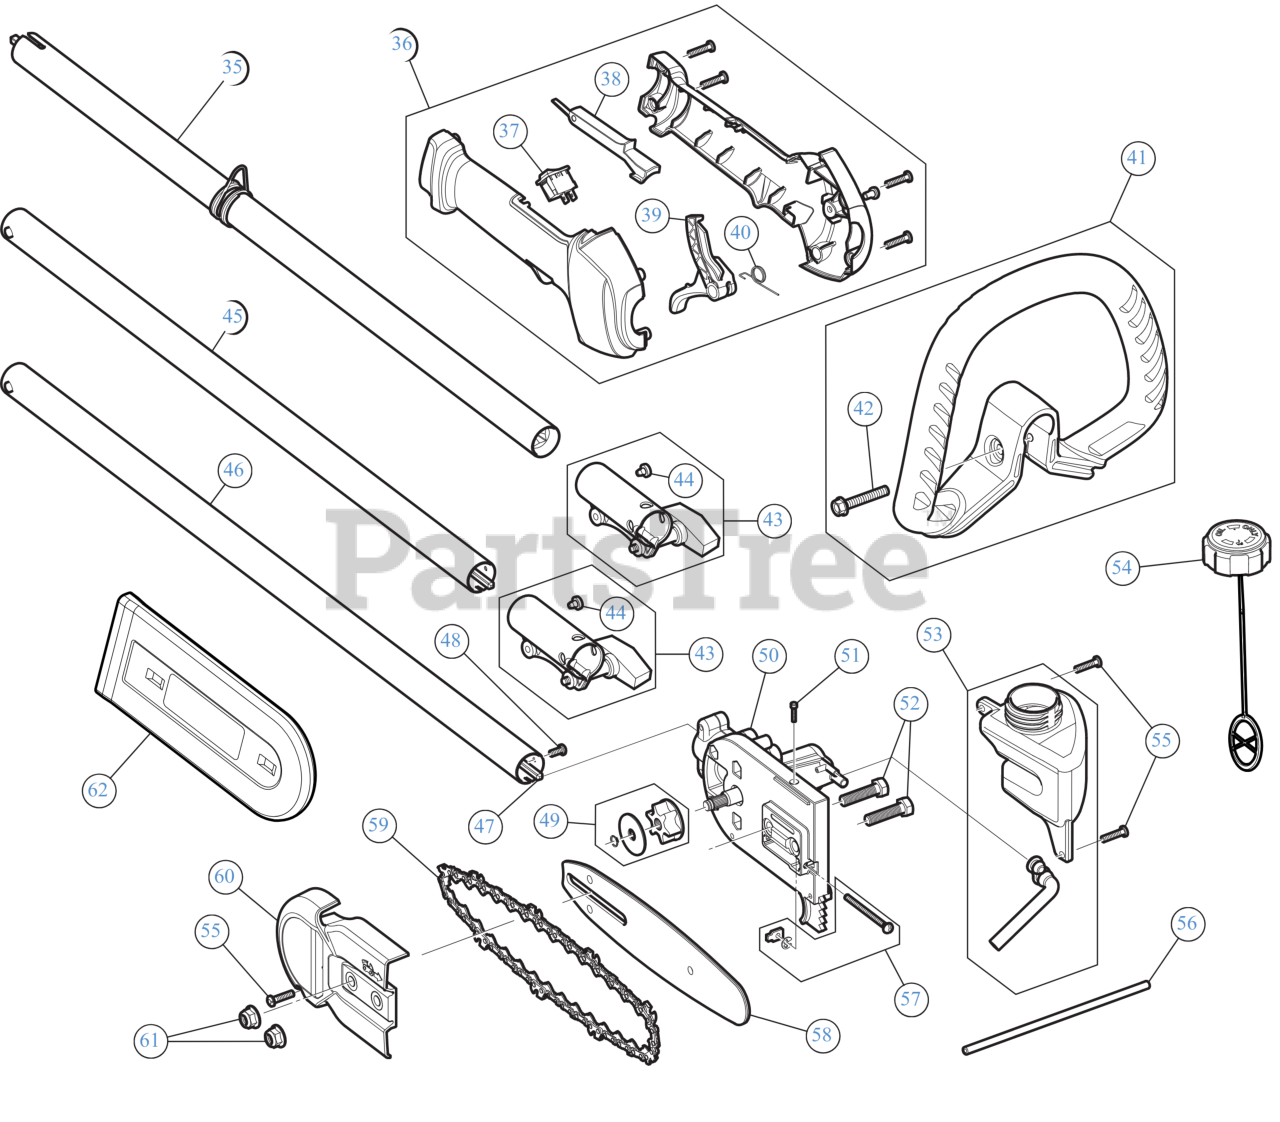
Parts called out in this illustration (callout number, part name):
35	BOOM ASSEMBLY UPR
36	THROTTLE GRIP ASSEMBLY
37	SW, MOMENTARY ON/O
38	LEVER LOCK OUT
39	THROTTLE TRIGGER
40	TRIGGER SPRING
41	HANDLE ASSEMBLY
42	BOLT 1/4-20X1 1/2
43	COUPLER ASSEMBLY
44	SCREW, 10-32X.250 TA
45	EXTENSION BOOM ASSEMBLY
46	LOWER DRIVE SHAFT HOUSING
47	FLEXIBLE DRIVE SHAFT
48	SCREW 1/4-20 X.500
49	SPROCKET ASSEMBLY
50	GEAR BOX ASSEMBLY
51	SCREW 4X40X.50
52	SCREW 5/16-18 x 1.25 GR5
53	OIL TANK ASSEMBLY
54	FUEL CAP ASSEMBLY
55	SCREW, #8-16X.750 PH
56	OIL LINE
57	CHAIN TENSION HDW
58	BAR 8" SPROCKET NOSE
59	CHAIN 8" 34 LINK .043 GAUGE
60	CHAIN GUARD
61	FLANGE LOCK NUT 5/16-18
62	8" SCABBARD
